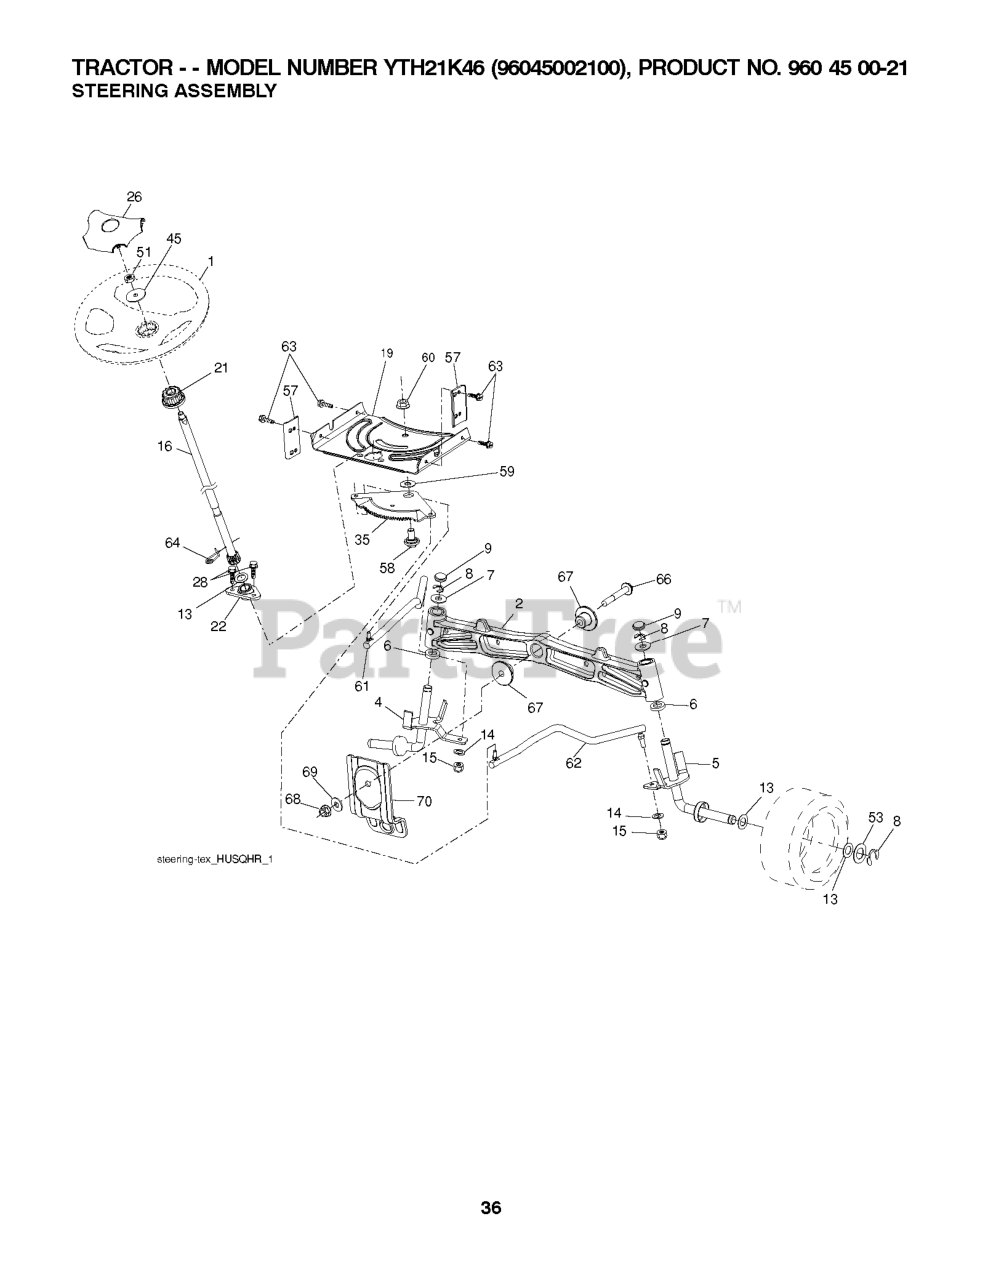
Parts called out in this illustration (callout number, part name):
1	WHEEL.STEER.HUSQ.SR.498.OVMLD
2	AXLE.CAST.IRON
4	SPINDLE.WELDED.LH.15"TEX
5	SPINDLE.WELDED.RH.15"T
6	THRUST WASHER
9	CAP.SPINDLE.BLACK
14	WASHER, LOCK 3/8
15	NUT CROWNLOCK 3/8-24
16	SHAFT, STEERING
19	PLATE.STEER.DDL.NLT/NG
21	ADAPTER, WHEEL STNG..
22	STEERING.SUPT.LOWER.
26	INSERT.CAP.WHL.STRG.HUSQ.PREM
28	SCREW, 3/8-16X3/4
35	GEAR.SECTOR.PLATE.DDL.
45	WASHER 9/16"ID, 2 3/8"OD
51	NUT.HEX.1/2-20
53	WASHER.HARDENED
57	BRACKET.UPSTOP.TEX
58	BOLT.SHOULDER.SECTOR.P
59	WASHER.THURST.SECTOR.S
60	NUT FLANGE LOCK 5/8-11
61	DRAGLINK.LH.BALLSTUD.D
62	DRAGLINK.RH.BALLSTUD.D
63	SCREW
64	RETAINER.CLIP.SPRING.S
66	BOLT HEX FGHD 7/16-14 X 3 SERR
67	BUSHING.PM.FRONT AXLE
68	NUT.LOCK.FLANGE.7/16
69	WASHER.1.5X.505X.118
70	BRKT.DECK.SUSPENSION.F
